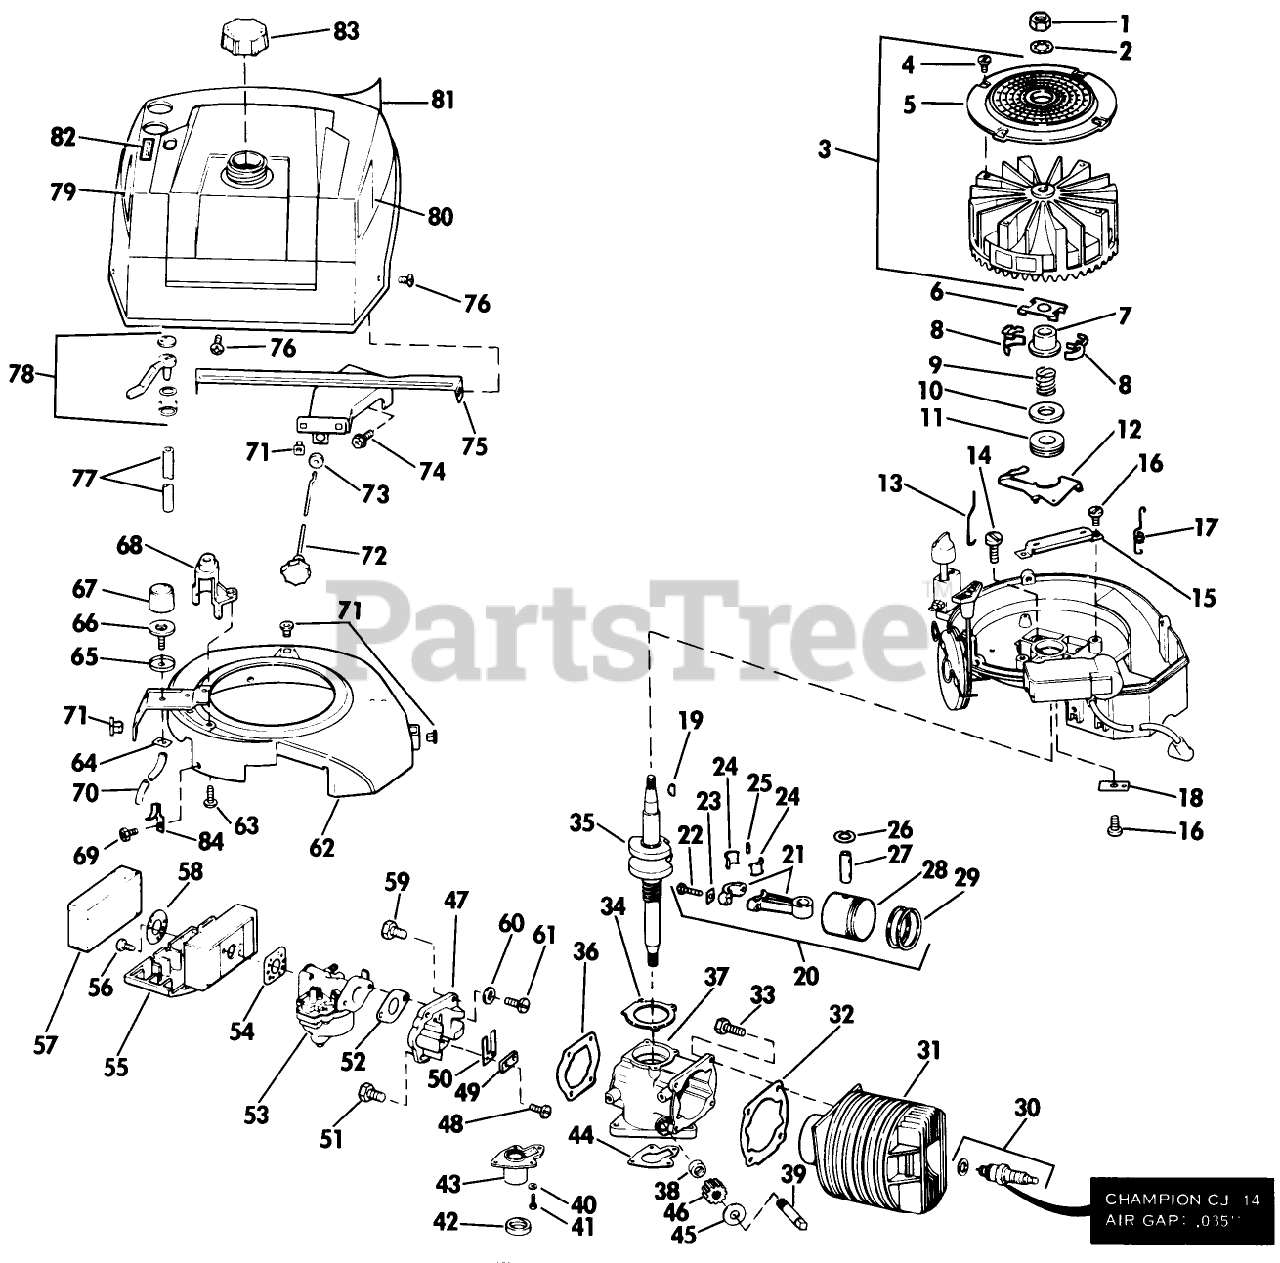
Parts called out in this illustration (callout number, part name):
4	SCREW F
7	COLLAR S
9	SPRING S
12	LEVER-GOVERNOR S
15	BRACKET
16	SCREW S
24	LINER ASM
26	RING-RETAINING
30	Spark Plug
32	GASKET S
34	GASKET S
36	GASKET S
43	GEAR COVER S
44	GASKET-CVR S
45	THRUST WASHER
46	GEAR, DR SHAFT S
47	REED PLATE AY. S
49	PLATE-BACKUP, REED
51	SCREW S
52	GASKET S
54	GASKET S
56	SCREW S
57	AIR FILTER S
58	WASHER S
59	SCREW S
64	LOCKNUT S
65	CUP-BULB
71	NUT-CLIP
74	SCREW S
75	BRACKET
76	SCREW S
